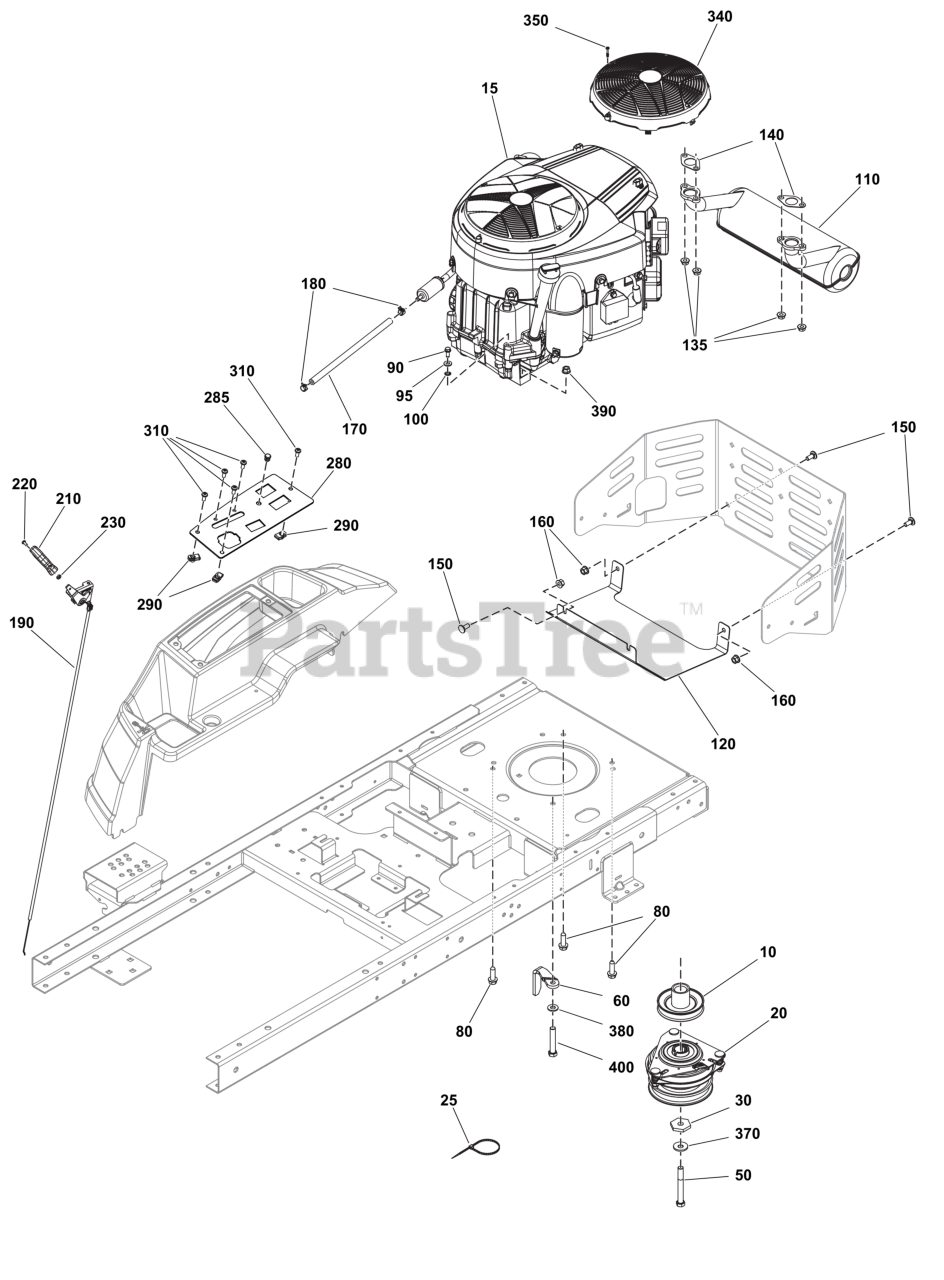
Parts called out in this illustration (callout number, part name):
10	ASSEMBLY-PULLEY
25	TIE, SELF LOCKING
30	WASHER, HEX, 0.453ID
50	CAPSCREW, Hex Head, Loctite, 7/16-20 x 3 1/2
60	GUARD, Belt
80	TAPTITE
90	SCREW, 1/4-20X0.625
95	WASHER
100	WASHER
120	SHIELD, Heat
140	GASKET, Exhaust
150	RHSSNB
160	NUT
170	HOSE, FUEL
180	CLAMP, Hose
190	CONTROL-THROTTLE
210	KNOB, THROTTLE
230	NUT, HEX, ZINC, #8-32
280	PANEL, Control (Choke & Hourmeter) Black
285	PLUG, Hole, .44" OD
290	BODY CLIP, 1/4-20 X 1
340	GUARD, Debris Screen
370	BELLEVILLE WASHER
380	WASHER
390	NUT
400	BOLT, 5/16-18 X 1-3/4
